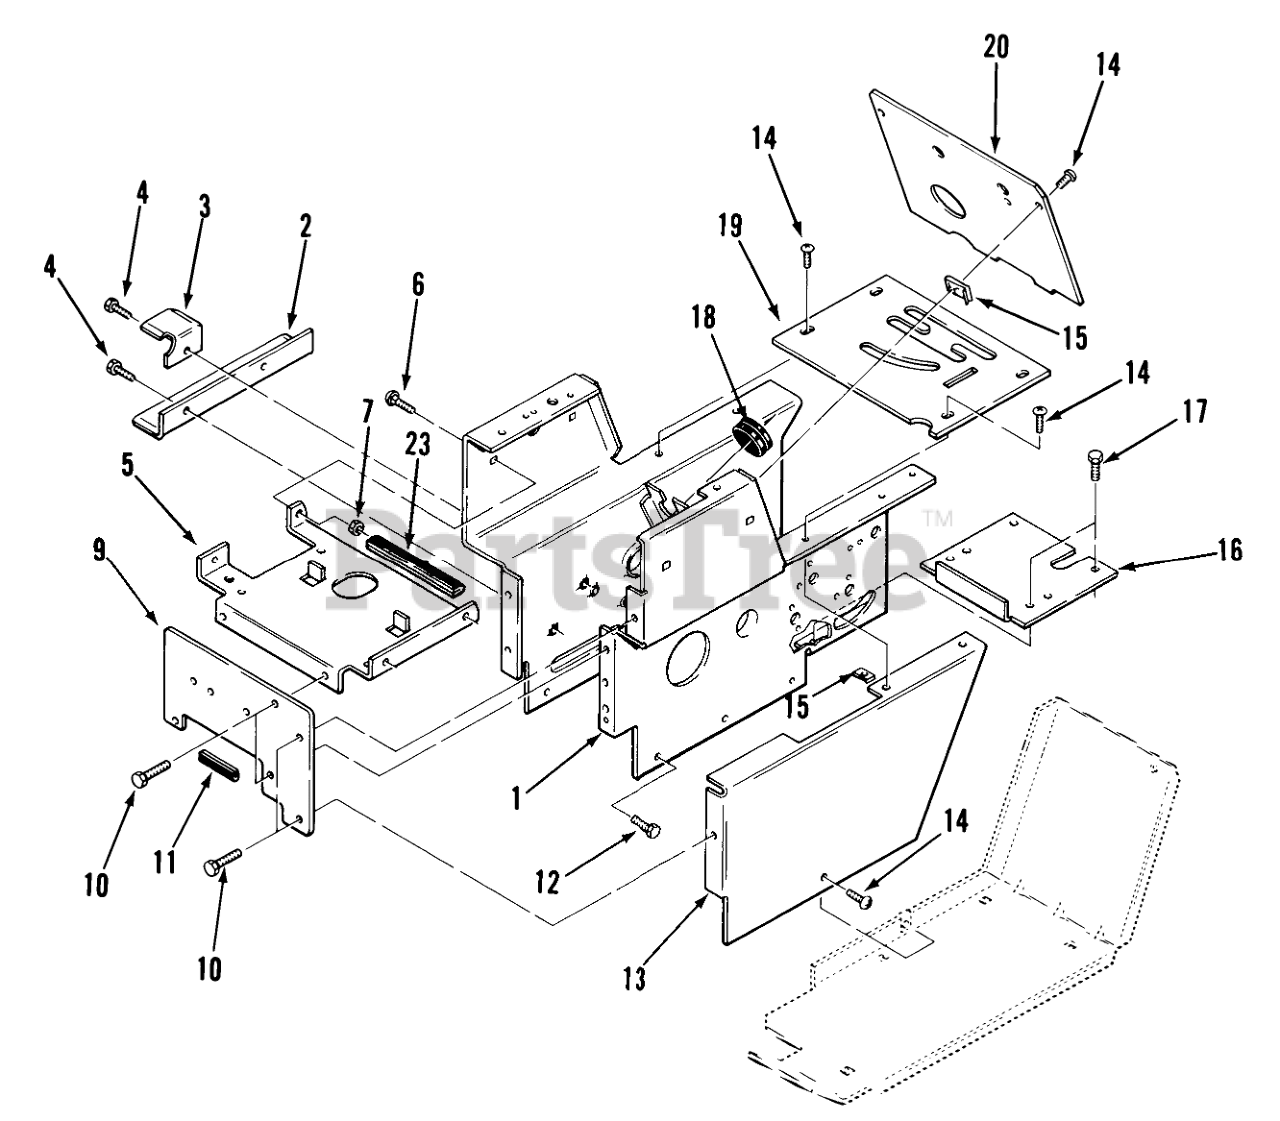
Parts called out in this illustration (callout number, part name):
2	ANGL-BLT GURD*B
3	BRCKET-BLT SUT*B
4	SCREW
6	CARRIAGE BOLT -4
10	SCREW
12	SCREW
17	SCREW
18	GROMMET
19	COVER SHIFT
22	WASHER 5/16 SAE
